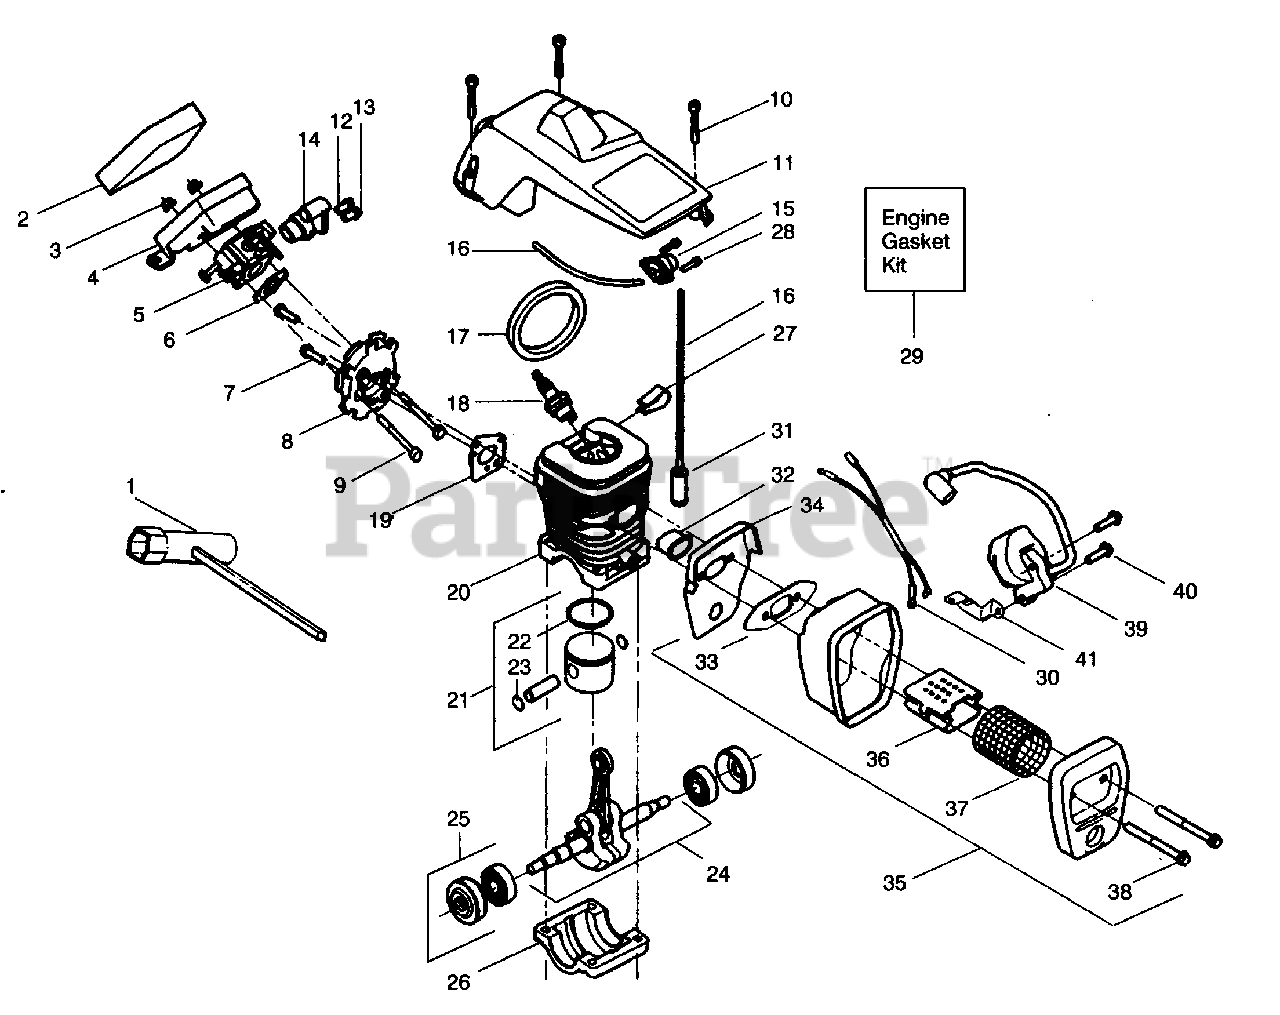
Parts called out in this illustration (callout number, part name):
1	Bar Wrench
2	Foam-Air Filter
4	Air Filter Housing
5	Carburetor Ass'y. Kit (Inc. 12 & 13)
6	Carb. Gasket
7	Screw
8	Carb. Adapter Kit (Inc. 9 & 17)
11	Cylinder Shield
12	Limiter Cap-High
13	Limiter Cap-Low
14	Grommet-Carb Adjust.
15	Primer Ass'y.
16	Primer Line Kit (Small Dia)
17	Air Box Seal
18	Spark Plug (CJ-7Y)
20	MODEL 230
20	MODEL 260
21	MODEL 230
21	MODEL 260
22	MODEL 230
22	MODEL 260
23	Retainer-Piston Pin
24	MODEL 230
24	MODEL 260
25	Seal & Bearing Ass'y.
26	Cap-Crankcase
27	Clip-High Tension Lead
28	Screw
29	Engine Gasket Kit (Inc. 6,17,19,33)
30	Wire Harness Ass'y.
31	Fuel Filter
32	Heat Insulator
33	Muffler Gasket
34	Muffler Back Plate
35	Muffler Ass'y. (Inc. 33-34 & 36-38)
36	Muffler Diffuser
37	Spark Arrestor Screen
39	Ignition Module
40	Screw
41	Ground Strap
